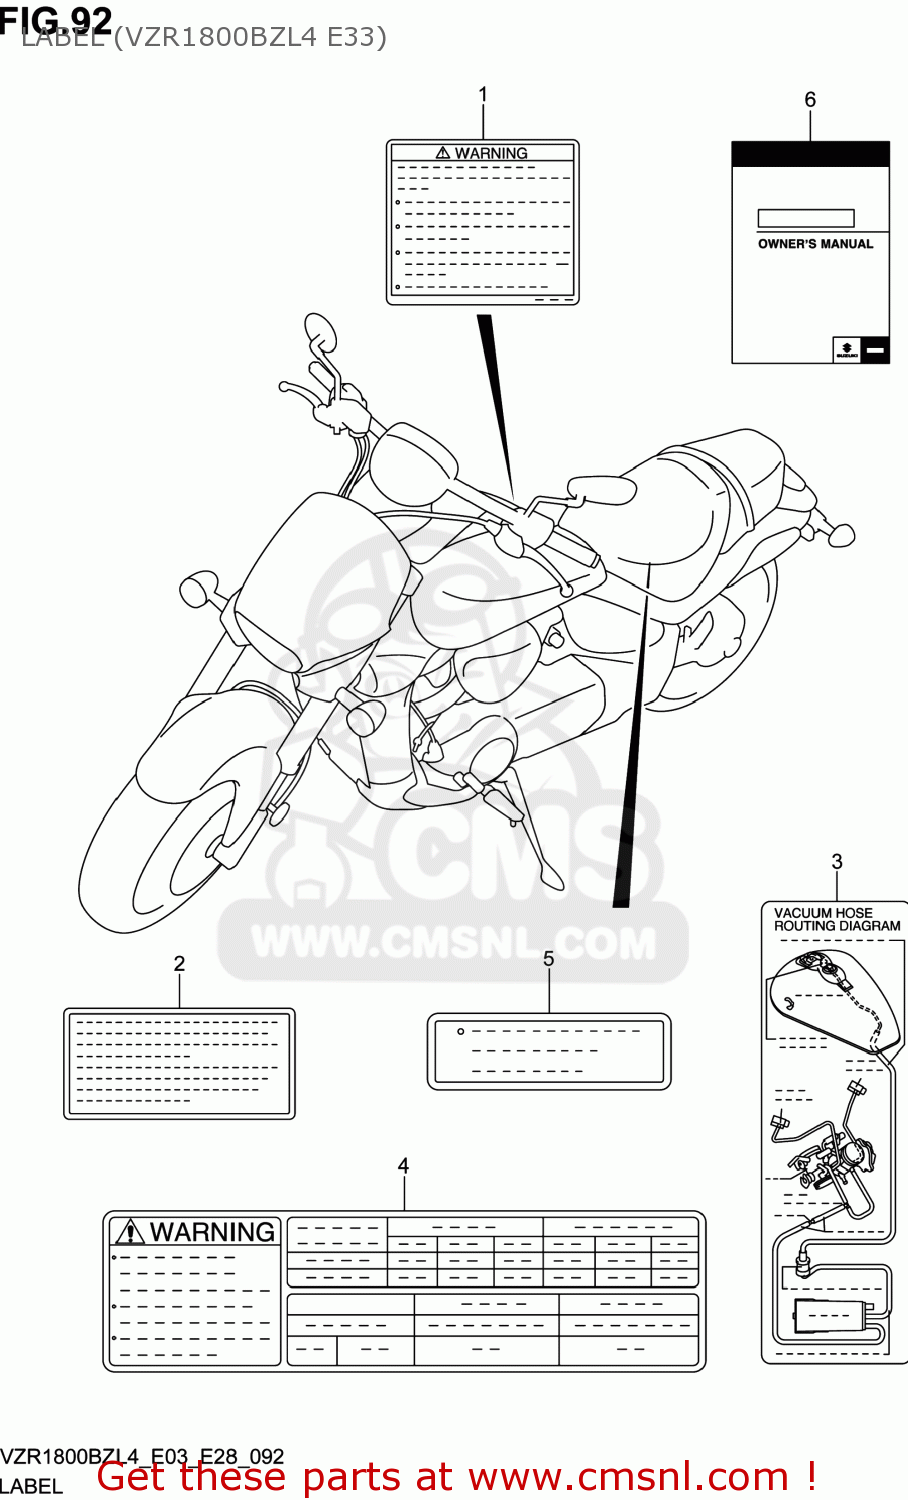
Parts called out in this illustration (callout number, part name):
1	LABEL,GENERAL WARNING
2	LABEL,MANUAL NOTICE
3	LABEL,VACUUM HOSE ROUTING
4	LABEL,TIRE INFORMATION
5	LABEL,FUEL INFORMATION
6	MANUAL,OWNER'S
